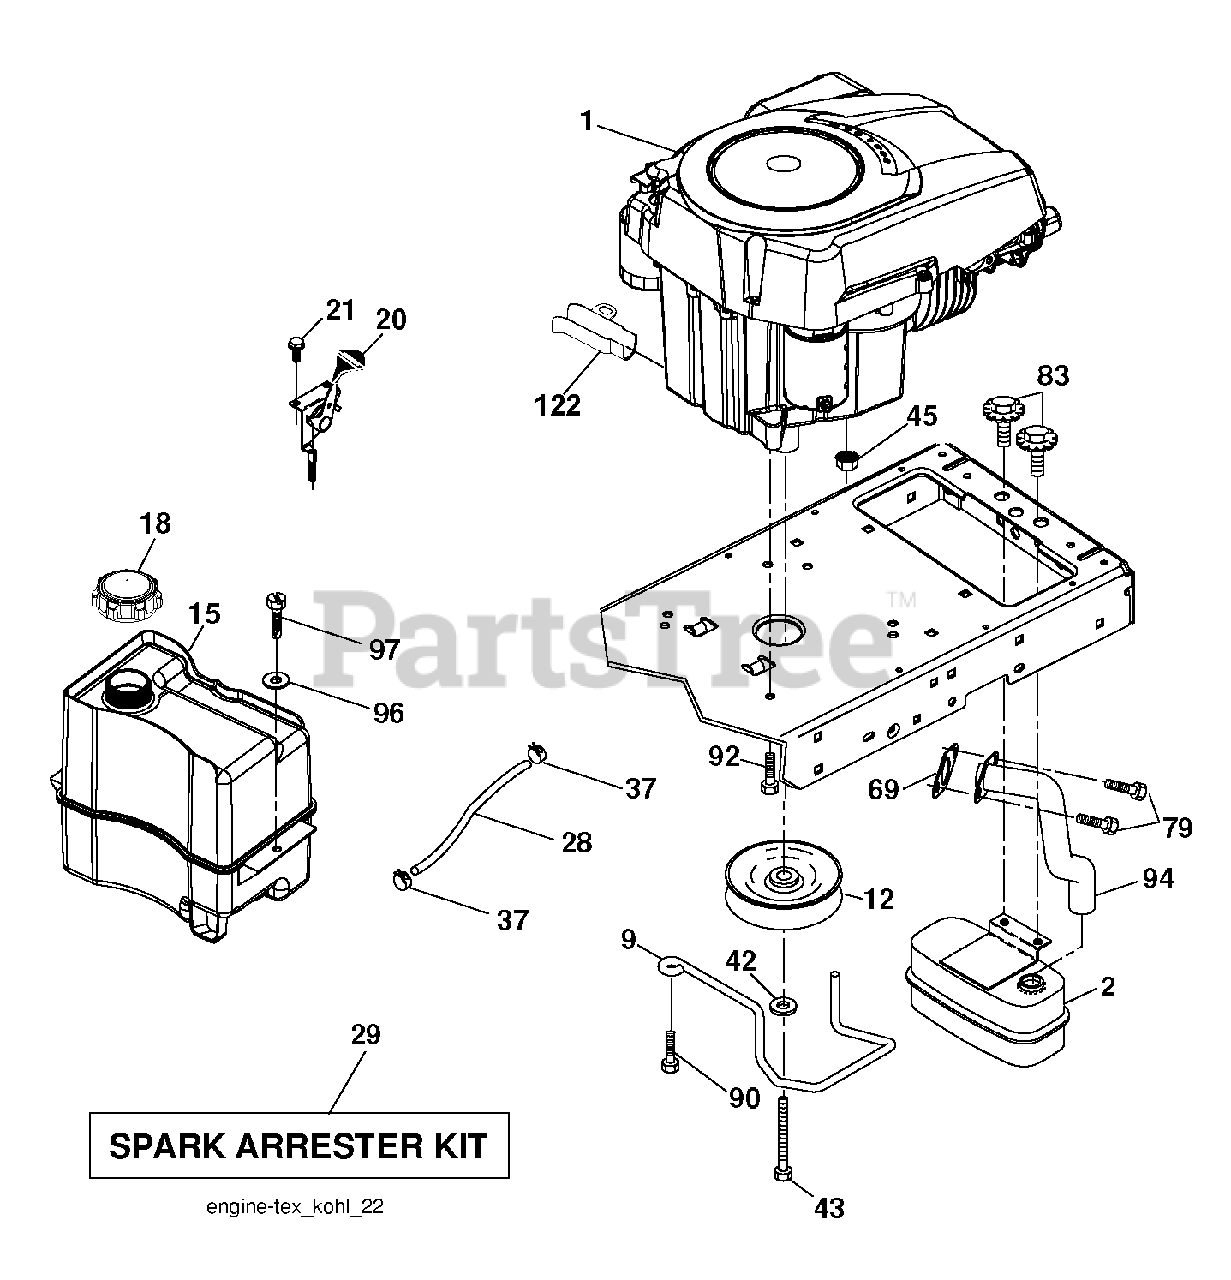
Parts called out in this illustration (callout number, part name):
2	MUFFLER.SINGLE.LRG.BRIGGS.KOHL
9	KEEPER BELT ENGINE
12	PULLY ENGINE
15	FUEL.TANK.ASM.NON-EPA
18	CAP ASM.FUEL.2.25"FR.
20	CONTROL.TH/CK.C.
21	SCREW.#10 X 0.750.BOS
28	LINE.FUEL.20
29	KIT.SPARK ARRESTOR 794945 B&S
37	HOSE CLAMP
42	LOCKWASHER
43	BOLT HEX 7/16-20X4-1/4"
45	NUT
69	GASKET.EXHAUST.KOHLER
79	SCREW.SOCKET HD.5/16-1
83	BOLT, 5/16-18 X 1 3/4
90	SCREW 3/8-16X1
92	SCREW 3/8-16X1
94	TUBE.EXHAUST.KOHLER.COURAGE
97	SCREW HEXWSHR 1/4-20X3/4
122	EXTENSION DRAIN OIL
